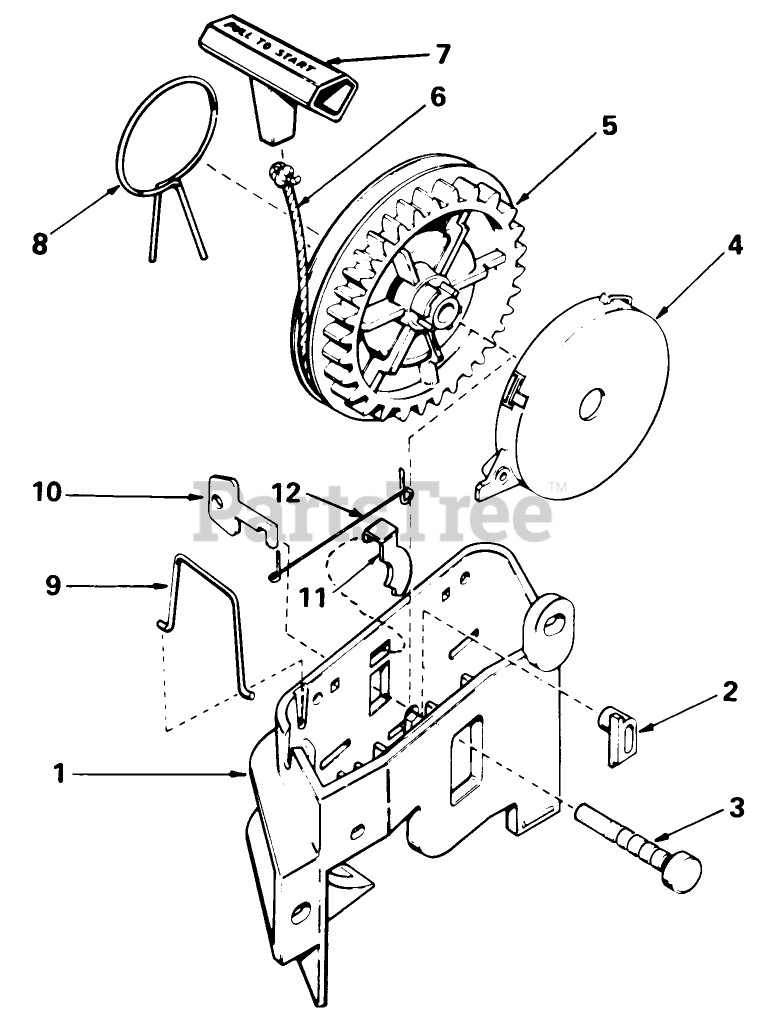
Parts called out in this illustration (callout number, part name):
1	Bracket Starter
2	Pawl, Locking Not used on all engine models)
3	Pin-Pulley
4	Spring Assy., Rewind (Incl. Ref. #3)
5	Pulley
6	Rope-Starter (98 cut to length)
7	Handle-Starter
8	Spring, Brake
9	Clip-Rope
10	Key (Not Used On All Engine Models
11	Pawl, Starter
12	Spring, Pawl
